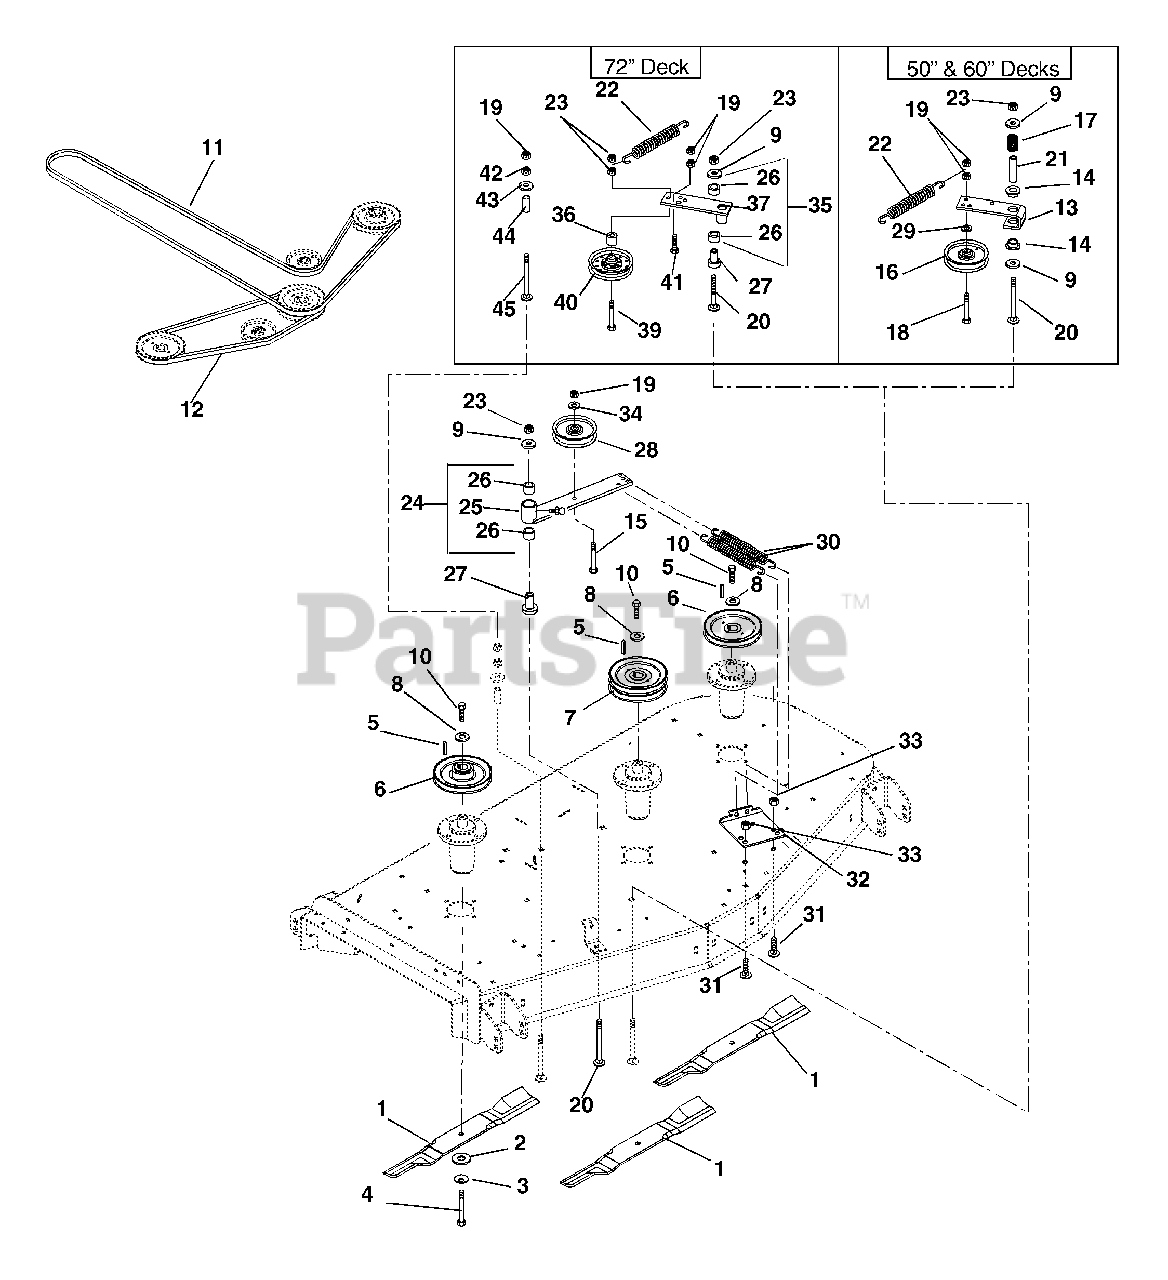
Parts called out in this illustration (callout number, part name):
1	Blade, 72" Tungsten
1	Blade, 60" Mower Tungsten Hi-Lift
1	Blade, 50" Mower Tungsten Hi-Lift
1	Blade, 50" Mower Sand Tungsten
1	Blade, 50" Mulching Tungsten
1	Blade, 60" Mulching Tungsten
1	Blade, 72" Mulching Tungsten
2	Washer, Flat .640 x 1.81 x .250
3	Washer-Bellville .63 x 1.625 x .14
4	Bolt, Blade
5	Key-Straight .25 x 1.00 x .25
6	Weldment, Spindle Sheave 7.00 (72" Deck)
6	Weldment, Spindle Sheave 6.00 (60" Deck)
6	Weldment, Spindle Sheave 5.00 (50" Deck)
7	Weldment, Sheave (Double) 7.25 (72" Deck)
7	Weldment, Spindle Sheave (Double) 6.25 (60" Deck)
7	Weldment, Spindle Sheave (Double) 5.25 (50" Deck)
8	Washer, Cupped, Serrated .375
9	Washer-Flat-Steel .531 x 1.25 x .100
10	Bolt-Hex .38-16 x 1.00 Grade 8
11	V-Belt, B-RMA 69.81 x .625 (72" Deck)
11	V-Belt, B-RMA 63.40 x .625 (60" Deck)
11	V-Belt, B-RMA 58.70 x .625 (50" Deck)
12	V-Belt, B-RMA 28.62 x .625 (72" Deck)
12	V-Belt, B-RMA 23.94 x .625 (60" Deck)
12	V-Belt, B-RMA 18.13 x .625 (50" Deck)
13	Arm,Idler Pivot
14	Bushing-Flange-Nylon .762 x 1.0 x .580 x 1.48
15	Bolt, Hex .38-16 x 3.00 Grade 5
16	Idler-V 4.00 x .377
17	Spring-Compression .085 x .80 x 1.00
18	Bolt-Hex .38-16 x 2.25 Grade 5
19	Nut-Locking-Center .38-16 (50" & 60" Decks)
19	Nut-Locking-Center .38-16 (72" Decks)
20	Bolt-Round Head Square Neck .50-13 x 3.50
21	Spacer .560 x .750 x 2.437 Steel
22	Spring, Extension
23	Nut-Locking-Center .50-13
24	Assembly, Idler Pivot Arm
25	Weldment, Idler Pivot Arm
26	Bearing, 1.00 x 1.12 x .75
27	Bearing, Pedistal Powdered Metal
28	Idler-Flat 4.00 x .38 (2.00 W)
29	Bushing .406 x .750 x .188
30	Spring, Extension
31	Bolt-Round Head Square Neck .38-16 x 1.00 Grade 5
32	Bracket, Spring
33	Nut-Locking-Nylon .38-16
34	Washer-Flat-Steel .375 x 1.125 x .065
35	Assembly, Idler Arm-Ground Drive
36	Spacer .51 x .75 x .62
37	Weldment, Idler Arm Ground Drive
38	Bolt-Round Head Square Neck .50-13 x 3.50 G5
39	Bolt-Hex .50-13 x 2.50 Grade 5
40	Idler-Flat-Pulley 6.75 x .510
41	Bolt-Hex .38-16 x 1.25 Grade 5
42	Nut-Locking-Nylon .38-16
43	Washer-Flat-Steel .406 x .812 x .065
44	Spacer .380 x .625 x 1.50
45	Bolt-Round Head Square Neck .38-16 x 2.75 Grade 5
